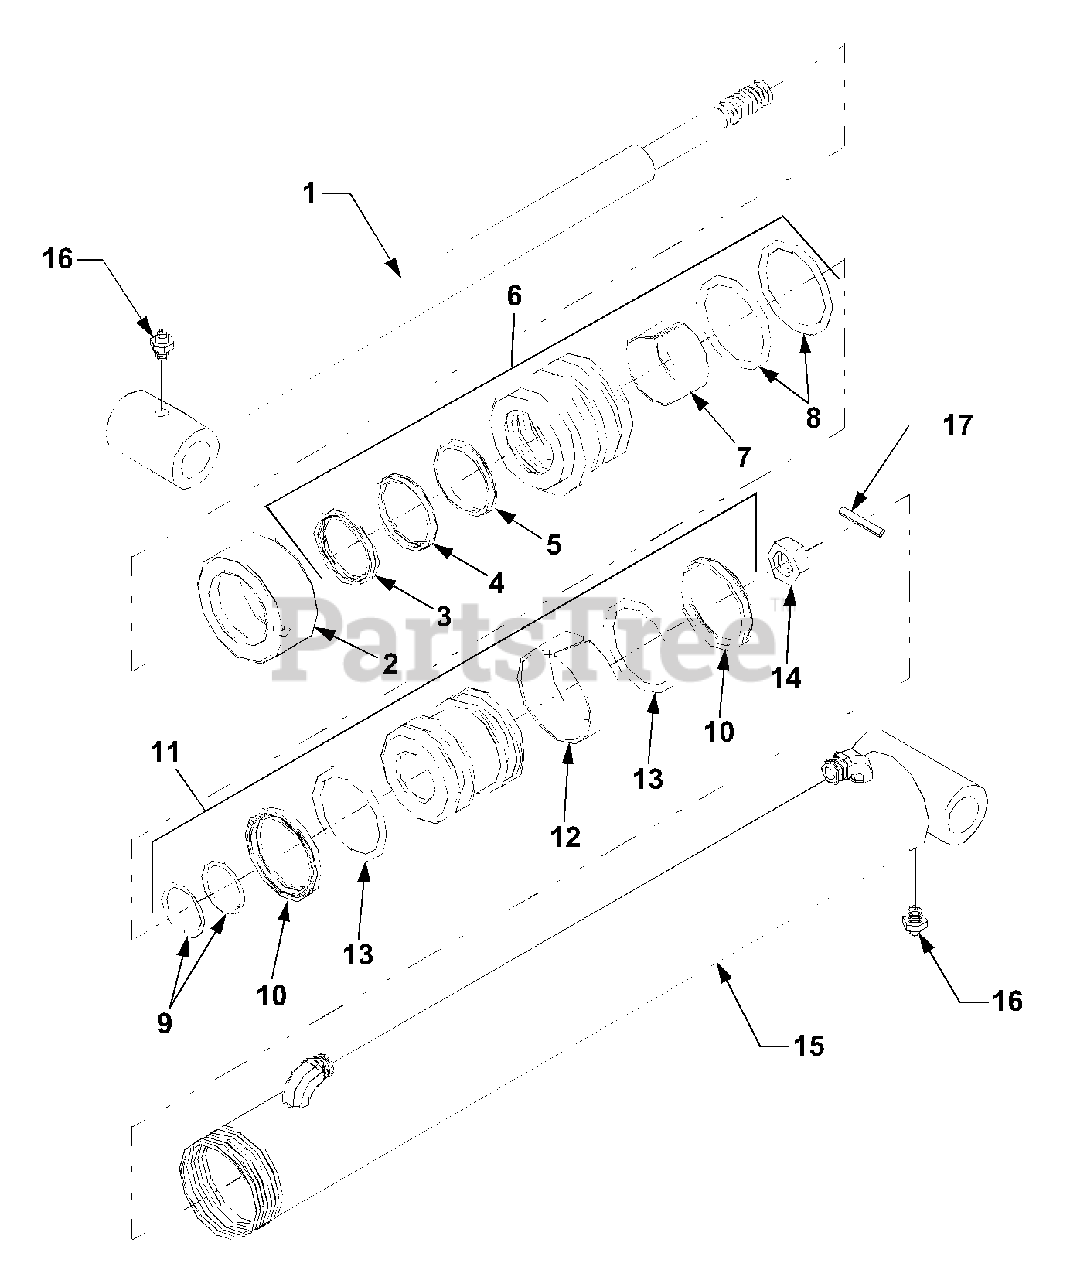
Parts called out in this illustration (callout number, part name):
1	Rod Ass'y.
4	Retainer (Rubber)
5	Retainer (Urethane)
6	Head and Seal Kit
11	Piston and Seal Kit
15	Tube Assembly
16	Grease Nipple
